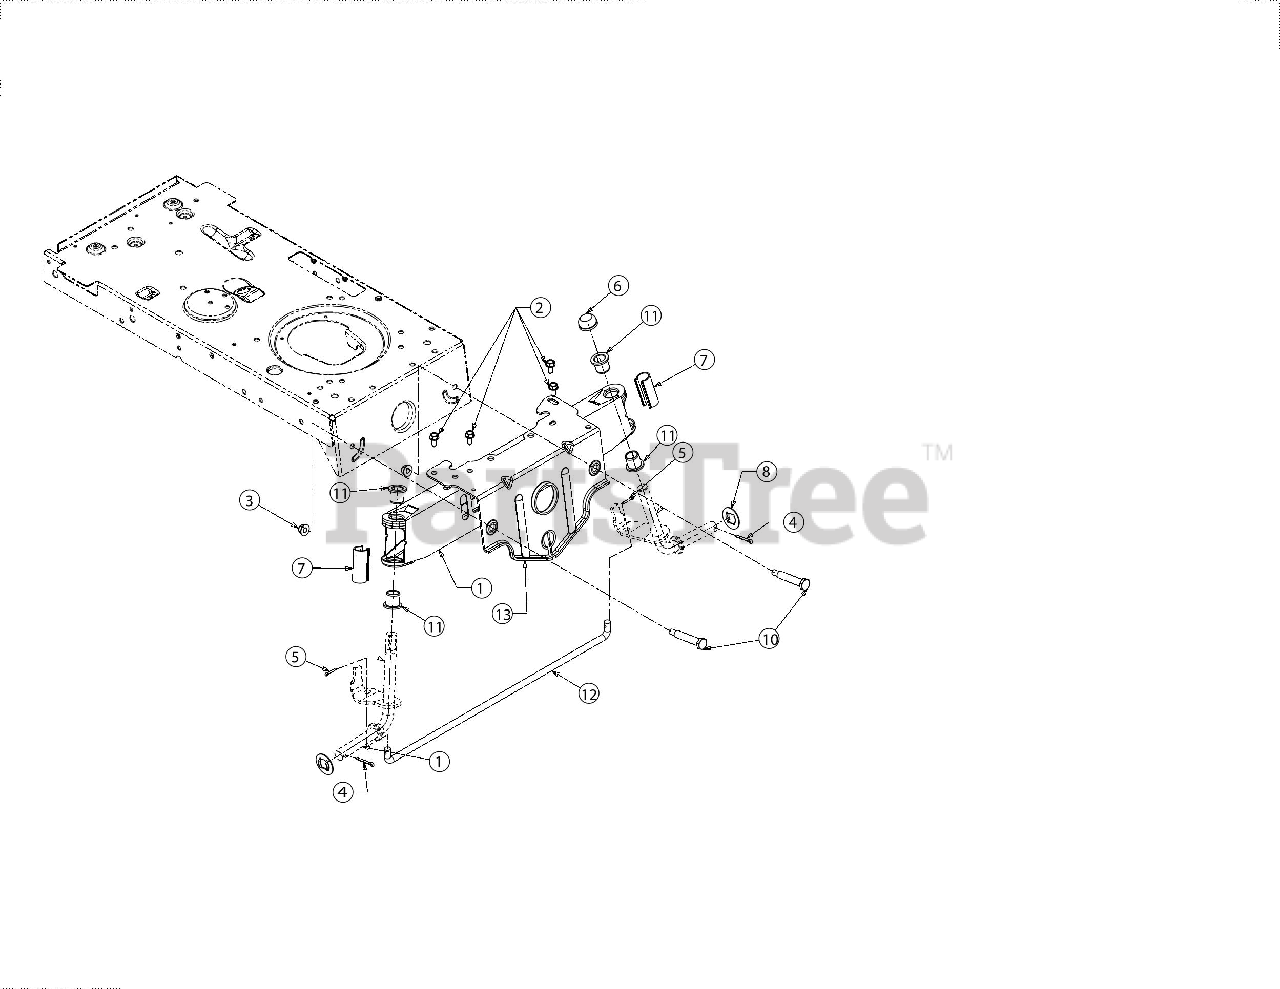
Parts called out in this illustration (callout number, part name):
2	SCREW 5/16-18 X .750
4	COTTER PIN-5/32 DIA
5	COTTER PIN
7	AXLE CAP
8	FLAT WASHER .781 ID x1.590 OD
10	SHOULDER SCREW .500X2.38X3/8-16
11	FLANGE BEARING .760 ID
12	FIXED TIE ROD
13	PIVOT BAR BRACKET
